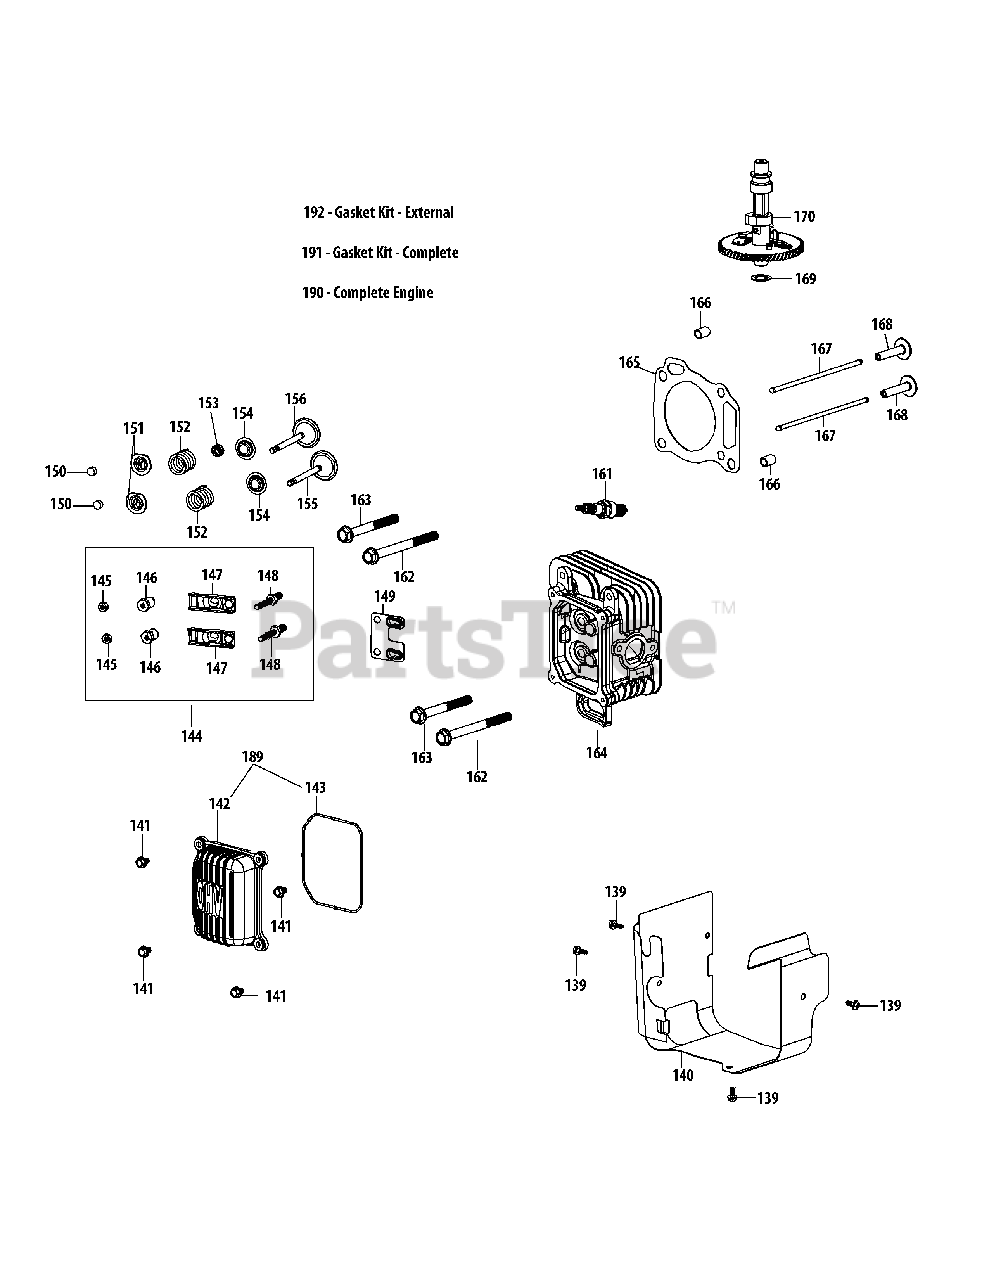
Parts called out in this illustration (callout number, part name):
139	Bolt M5×10
141	Valve Cover Bolt
142	Valve Cover
143	Valve Cover Gasket
144	Rocker Arm Assembly
145	Jam Nut
146	Fulcrum Nut
147	Rocker Arm
148	Rocker Arm Stud
149	Push Rod Guide
150	Exhaust Valve Adjuster
151	Exhaust Valve Spring Retainer
152	Valve Spring
153	Intake Valve Seal
154	Valve Spring Retainer
155	Valve Kit
156	Valve Kit
161	Spark Plug/F6Rtc
162	Bolt M10×1.25×85
163	Bolt /M10×1.25×65
164	Cylinder Head Assembly
164	Cylinder Head Kit
165	Cylinder Head Gasket
166	Cylinder Head Dowel 12×16
167	Push Rod Kit
168	Tappet
169	Camshaft Thrust Washer
170	Camshaft Assembly
189	Valve Cover Kit
190	Complete Engine
191	Gasket Kit - Complete
192	Gasket Kit - External
